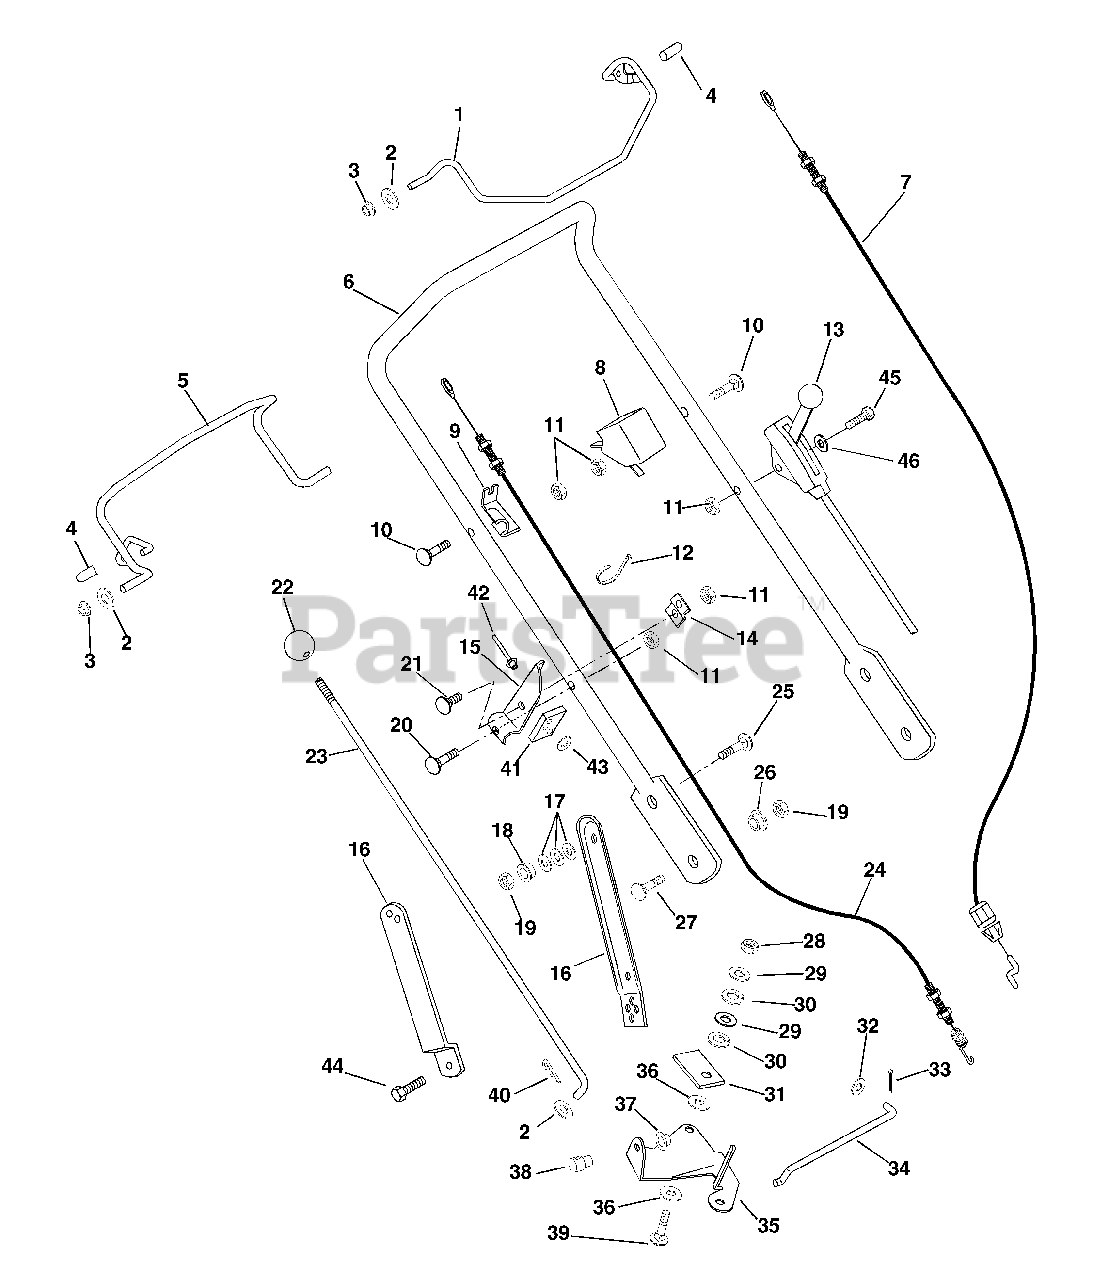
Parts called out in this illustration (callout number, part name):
1	ENGINE BAIL
2	@WSHR-FL-STL.344X.688X.065YWZC
3	BSHG-FLG .325X.444X.440X.560
4	CAP, VINYL, .25 ID
5	TRACTION BAIL
6	HANDLEBAR SELF-PROPELLED
6	HANDLEBAR - PUSH
7	ENGINE CONTROL CABLE
7	ENGINE CABLE
8	SWITCH-CABLE ANCHOR
9	CABLE ANCHOR, RH
9	CABLE ANCHOR-LH
10	BLT-RDHDXLSQNK.25-20X1.25 G5ZC
11	@NUT-LK-CTR .25-20 YWZC
12	CABLE TIE LG 5-1/2
13	THROTTLE CABLE
14	BRACE, SPEED CONTROL
15	BRACKET, SPEED CONTROL
16	LINK, HANDLEBAR ADJUSTMENT LH
16	LINK, HANDLEBAR ADJUSTMENT RH
16	BRACKET, HANDLEBAR
17	WASHER, BELLEVILLE YWZC
18	BSHG-FLG .325X.500X.513X.875
19	@NUT-LK-CTR .31-18 YWZC
20	@BLT-RDHDSQNK .25-20X1.50 G5YZ
21	@BLT-RDHDSQNK .25-20X.50 G5YZ
22	KNOB, BALL 5/16-18 X 1.5
23	ROD-SPEED CONTROL
24	TRACTION CABLE
25	@BLT-RDHDSQNK .31-18X1.00 G5YZ
26	BSHG, FLG .325X.499X.26X.88
27	@BLT-RDHDSQNK .31-18X.75 G5YZ
27	@BLT-RDHDSQNK .31-18X1.00 G5YZ
28	@NUT-LK-CTR .38-16 YWZC
29	@WSHR-FL-STL.406X.812X.065 YWZ
30	WSHR-LK .375X.115 HVY YWZC
31	PRESSURE FLANGE
32	@WSHR-FL-STL.281X.62X.065 YWZC
33	@PIN-CTR .06X.50 EXTPRSQCT YWZ
34	SHIFT LINK
35	BELL CRANK, SPEED CONTROL
36	FRICTION WASHER
37	CAP, 3/8 ROD YWZC
38	SWIVEL
39	@BLT-RHDSSQNK .38-16X1.25 G5YZ
40	PIN-HAIR INT .08X.18X1.18 YWZC
41	SUPPORT PAD
42	RVT .187X.575 DOME AL BLACK
43	@WSHR-FL-STL.219X.50X.049 YWZC
44	@BLT-HEX .31-18X.75 GR5 YWZC
45	@BLT-HEX .25-20X1.75 GR5 YWZC
46	@WSHR-FL-STL.250X.56X.049 YWZC
